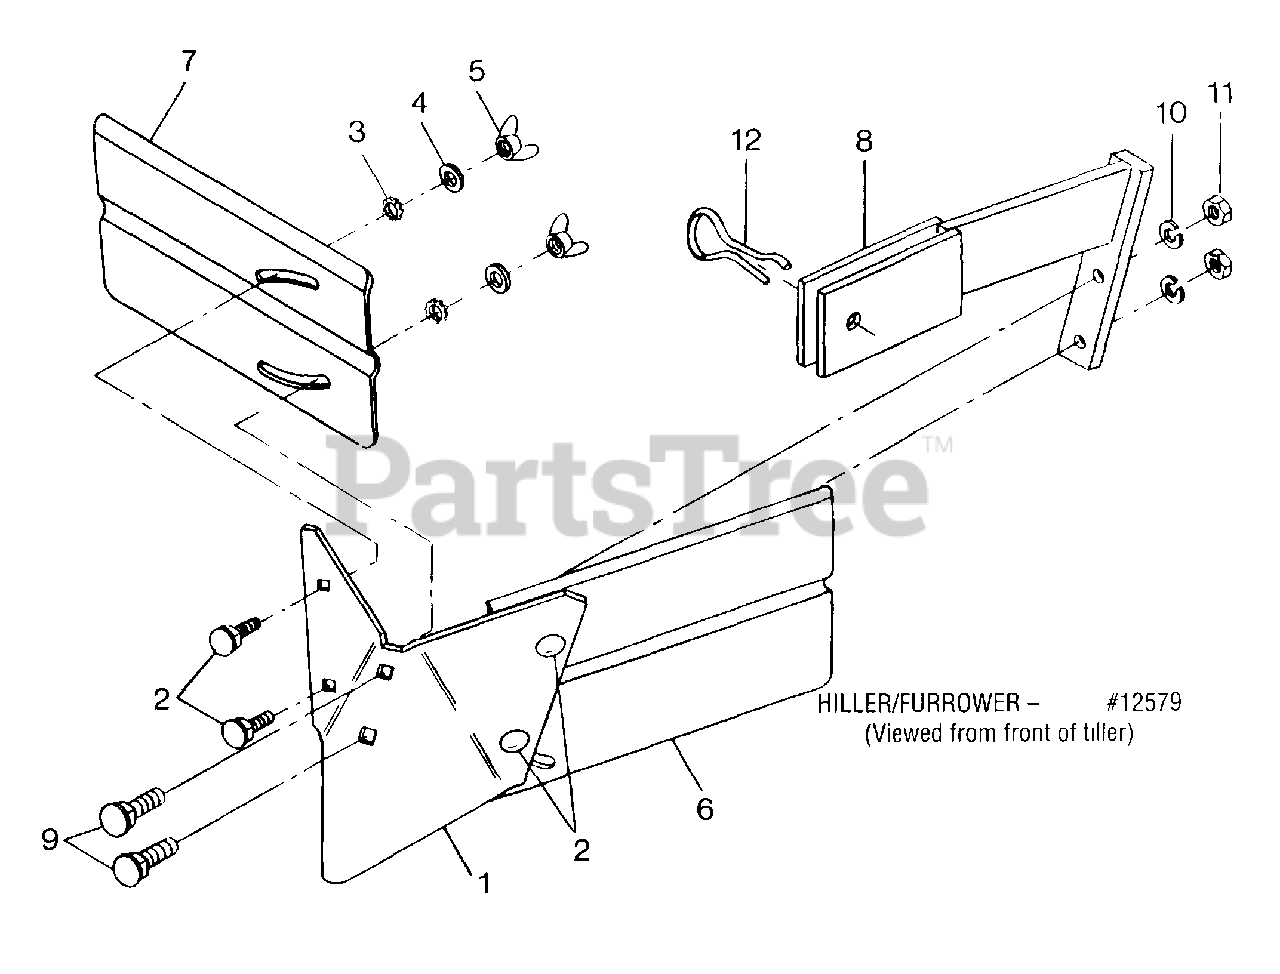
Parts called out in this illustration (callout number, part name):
1	Furrower-blade only
2	Carriage Bolt-5/16-18 x 3/4
3	Star Washer-external tooth, 5/16
4	Plain Washer-5/16 S A E
5	Wing Nut-5/16-18
6	Hiller Wing-left
7	Hiller Wing-right
8	Bracket-blade mounting
9	Carriage Bolt-blade mounting, 3/8-16 x 1-1/2
10	Lockwasher-3/8, plated
11	Nut-hex, 3/8-16, plated
12	Pin-clinch
